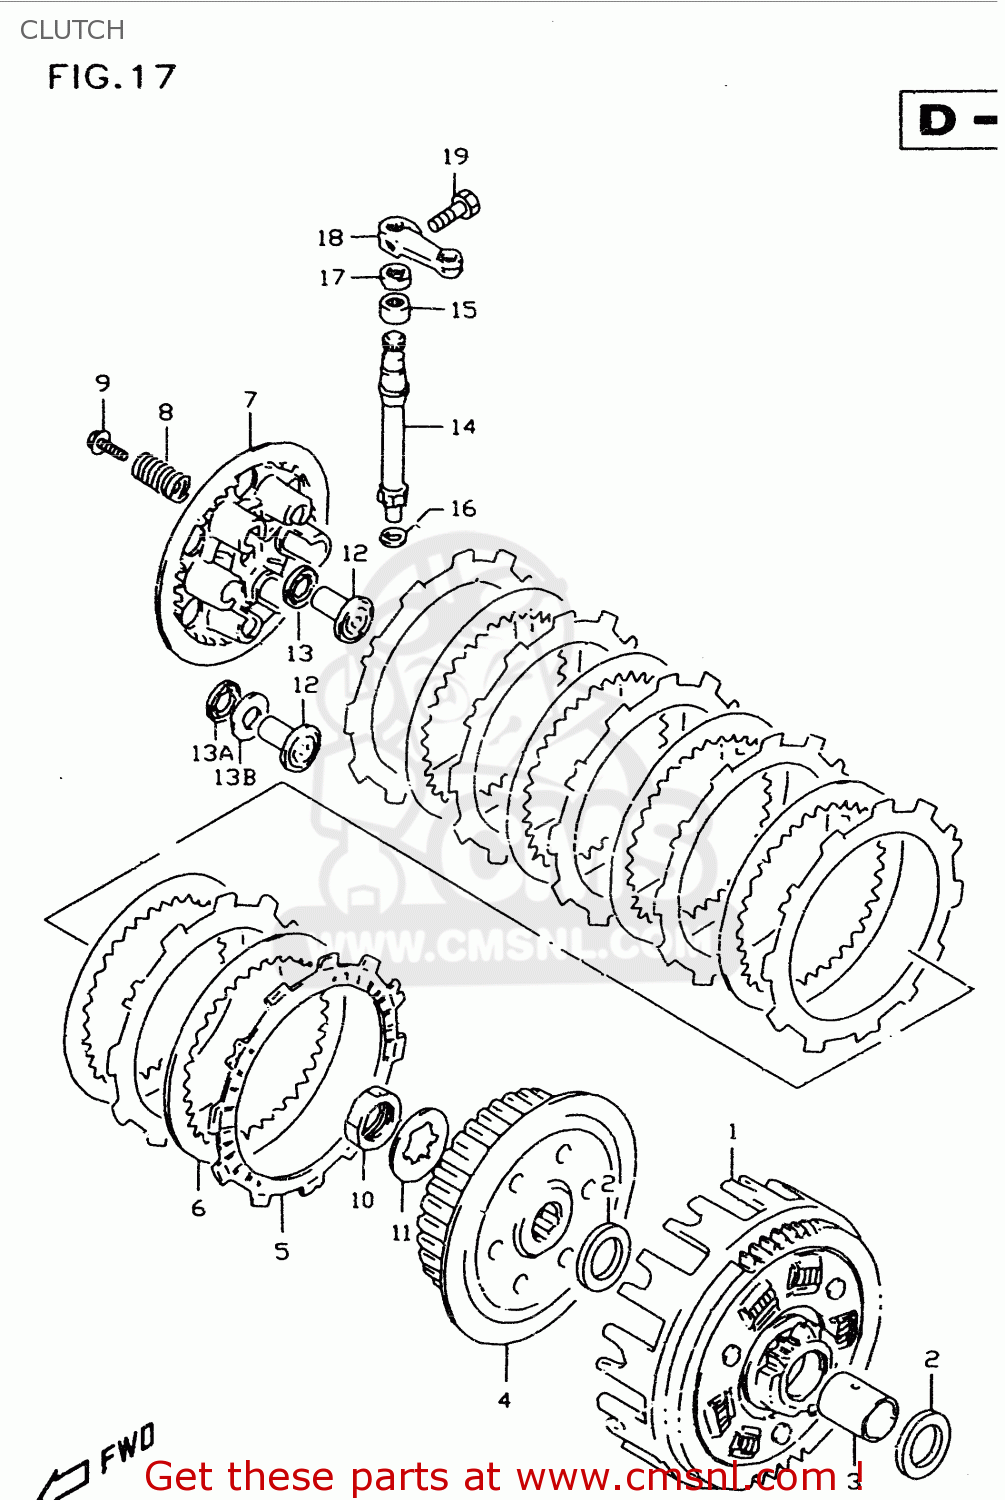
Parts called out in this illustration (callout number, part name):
1	GEAR ASSY,PRI DRIVEN(64/15
2	WASHER
3	SPACER(20X25X29)
4	HUB,CLUTCH SLEEVE
5	PLATE,CLUTCH DRIVE (NAS)
6	PLATE,CLUTCH DRIVEN T: (NAS)
7	DISC,CLUTCH PRESSURE
8	SPRING
9	BOLT 5X16
10	NUT
11	WASHER,LOCK
12	RACK,CLUTCH RELEASE
13	BEARING(10X22X2.8)
13A	BEARING(10X24X2)
13B	WASHER
14	PINION,CLUTCH RELEASE
15	BEARING(12X16X10)
16	WASHER
17	SEAL,OIL(10X17X5)
18	ARM,CLUTCH RELEASE
19	BOLT
